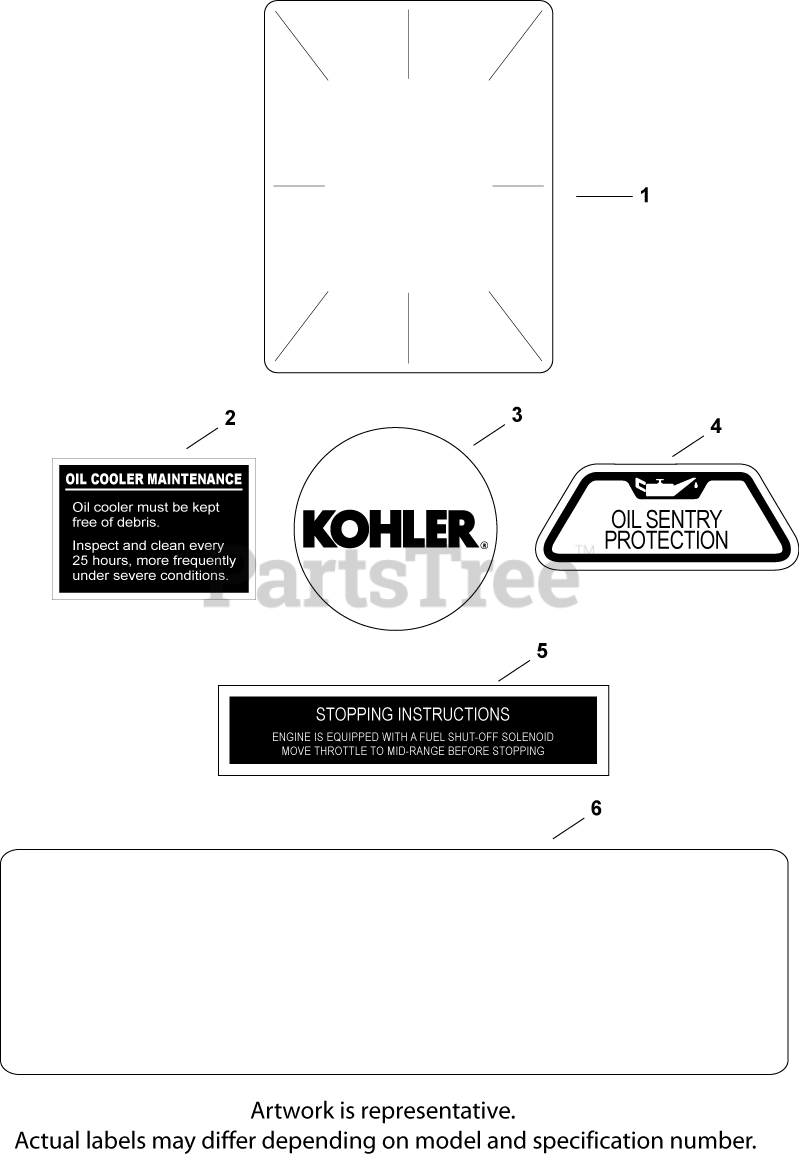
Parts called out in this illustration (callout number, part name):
1	DECAL, CLEAR LAMINATE USE 25 113 70-S
2	DECAL, OIL COOLER - (#DSC)
3	LABEL, (ROUND KOHLER GOLD)-USE 24 113 18
4	DECAL, OIL SENTRY - (#DSC)
5	DECAL, STOPPING INSTRUCTION
6	DECAL, 23 HP - (#24113216S)
